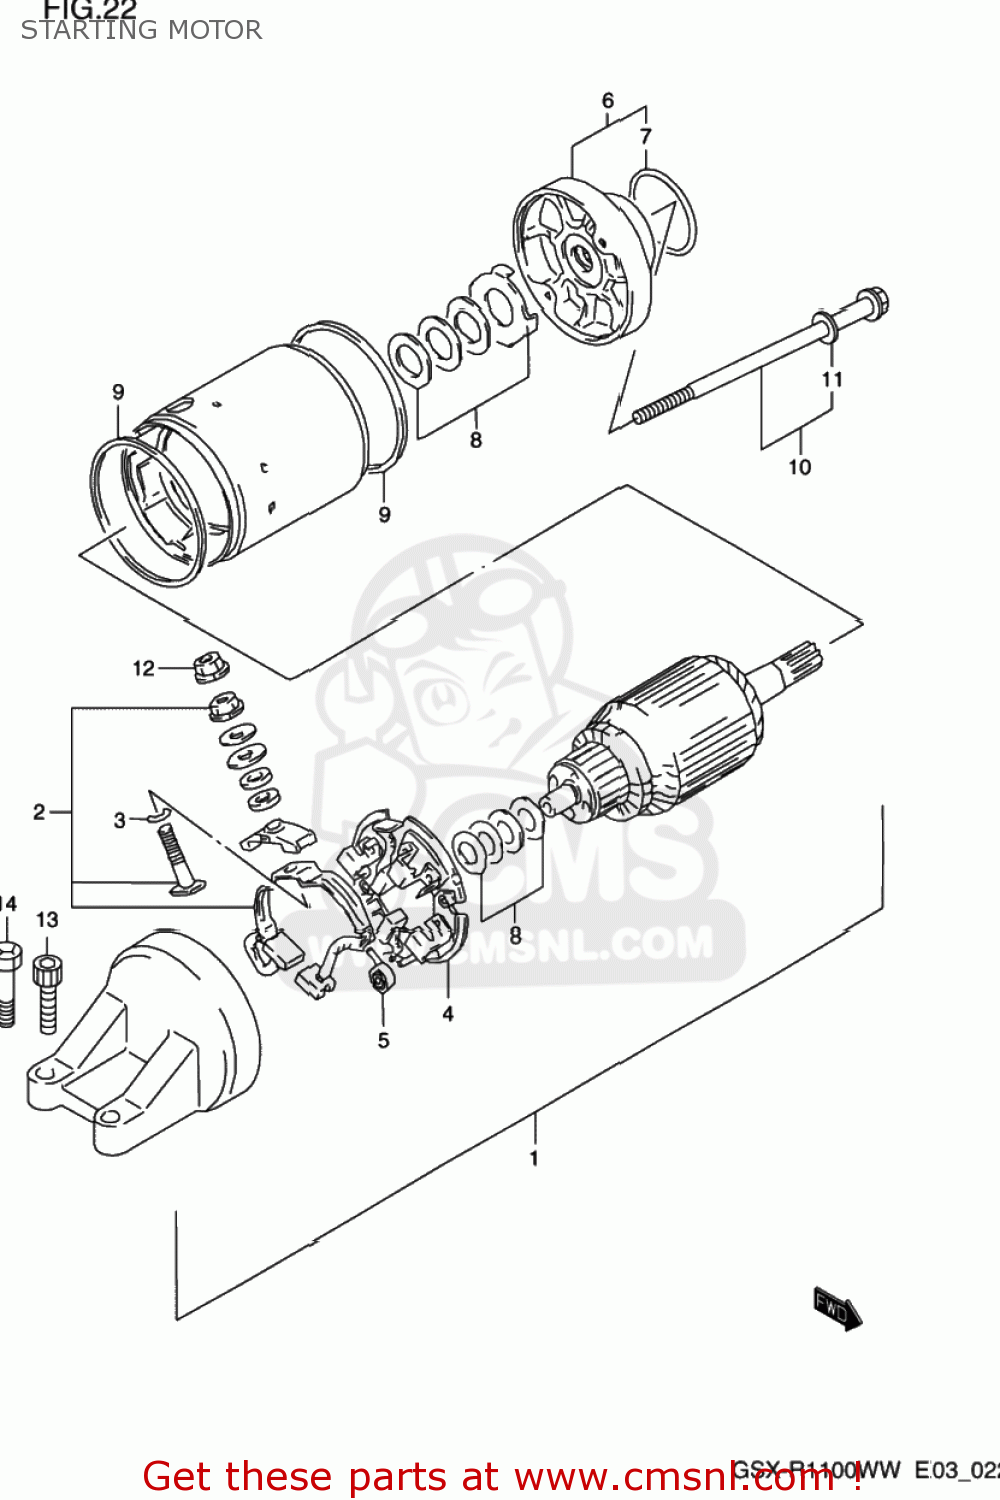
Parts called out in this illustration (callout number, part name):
1	MOTOR ASSEMBLY,STARTING
2	TERMINAL SET,BRUSH,PLUS
3	O RING
4	HOLDER,BRUSH
5	SPRING
6	HOUSING
7	O-RING
8	SHIM SET,STARTING MOTOR
9	O RING
10	BOLT
11	O RING
12	NUT
13	BOLT
14	SCREW (6X25)
